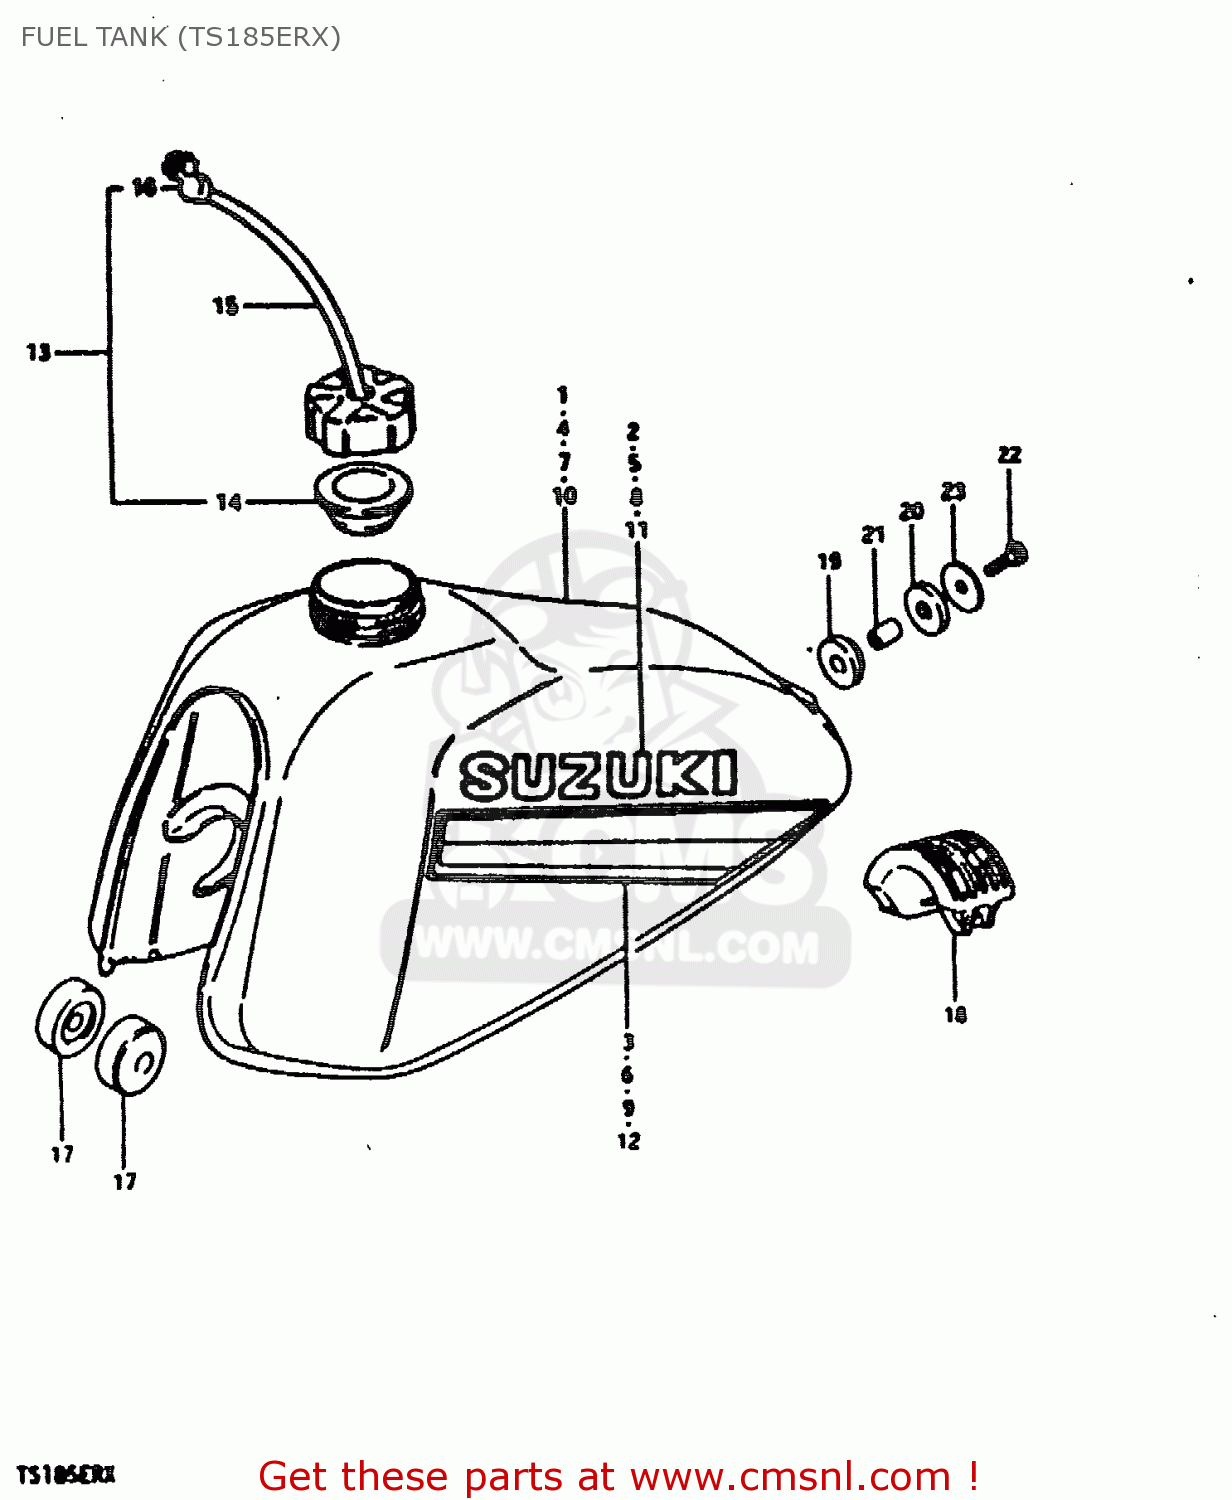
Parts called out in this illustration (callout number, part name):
1	TANK, FUEL (BLUE)
2	EMBLEM
3	TAPE SET
4	TANK, FUEL (YELLOE)
5	EMBLEM(BLACK)
6	TAPE SET
7	TANK, FUEL (RED)
8	EMBLEM
9	TAPE SET
10	TANK, FUEL (WHITE)
11	EMBLEM(BLACK)
12	TAPE SET
13	CAP SET,FUEL TANK
14	GASKET,FUEL TANK CAP (NAS)
15	HOSE
16	CLAMP,FUEL TANK BREATHER HOSE
17	CUSHION
18	CUSHION,FUEL TANK
19	CUSHION
20	CUSHION
21	SPACER(8.5X12X19)
22	BOLT (8X30)
23	WASHER (8.5X29X1.6)
